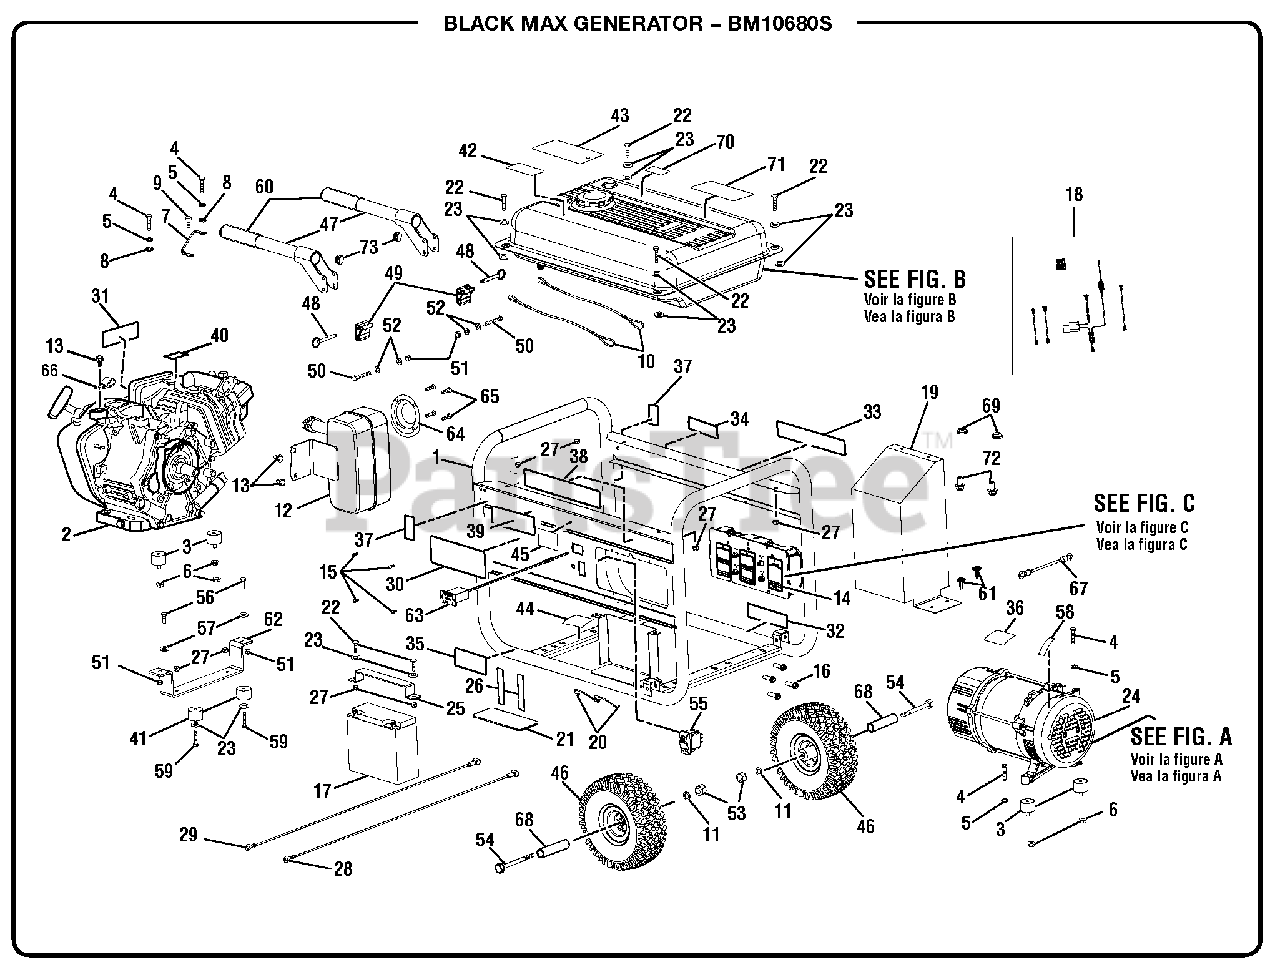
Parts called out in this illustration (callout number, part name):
1	Carrier Assembly
4	Bolt (5/16-18 x 1-1/2 in., Hex Hd.)
5	Lock Washer (5/16 in.)
6	Flange Nut (5/16-18, Hex Hd.)
7	Ground Wire Assembly
8	Star Washer (5/16 in.)
9	Bolt (5/16-18 x 3/4 in., Hex Hd.)
10	Lanyard (3/16 in.)
11	Washer (3/8)
13	Bolt (5/16-24 x 5/8 in.)
14	Control Panel Assembly
15	Screw (6-20 x 3/8 in.)
16	Bolt (3/8-16 x1.25 in.)
17	Battery
18	Wire Harness
19	Heat Shield
20	Cord Retainer
21	Battery Box Gasket
22	Bolt (1/4-20 x 1 in., Hex Hd.).
23	Washer (1/4 in.)
24	Generator Head w/AVR
25	Battery Hold Down Bracket
26	Gasket (Battery Hold Down Bracket)
27	Lock Nut (1/4-20)
28	Battery Cable (Red)
29	Battery Cable (Black)
30	Logo Label
31	Starting Instructions Label
32	Hot Surface Label
33	Danger Label
34	Fire Danger Label
35	Engine Lubricant Label
36	Data Plate Label
37	Locking Pin Label
38	Yamaha Label
39	Electric Start Label
40	Choke Label
41	Rubber Feet
42	CPSC Label
43	Danger Hang Tag
44	Inquires Label
45	Combustion Warning Label
47	Handle Assembly
48	Release Pin (5/16 x 2 in.)
49	Handle Bracket Spacer
50	Bolt (5/16-18 x 1-1/2 in., Hex Hd.)
51	Lock Nut (5/16)
52	Washer (5/16 in.)
53	Lock Nut (3/18-16 )
55	Start Switch w/Lock
56	Bolt (5/16-18 x 1 in., Hex Hd.)
57	Flat Washer (5/16 in.)
58	Ground Label Icon
59	Bolt (1/4-20 x 1-1/2 in., Hex Hd.)
60	Handle Grip
61	Screw (8 x .75 in.)
62	Front Foot
63	Voltage Meter
64	Spark Arrestor
65	Screw (8-32 x 3/8 in., Pan Hd.)
66	J-Clamp (1/2 in.)
67	Bonding Wire
69	Flange Nut (M6)
70	E85 Label
71	Electric Start Label
72	Bolt (M6 x 12 mm)
